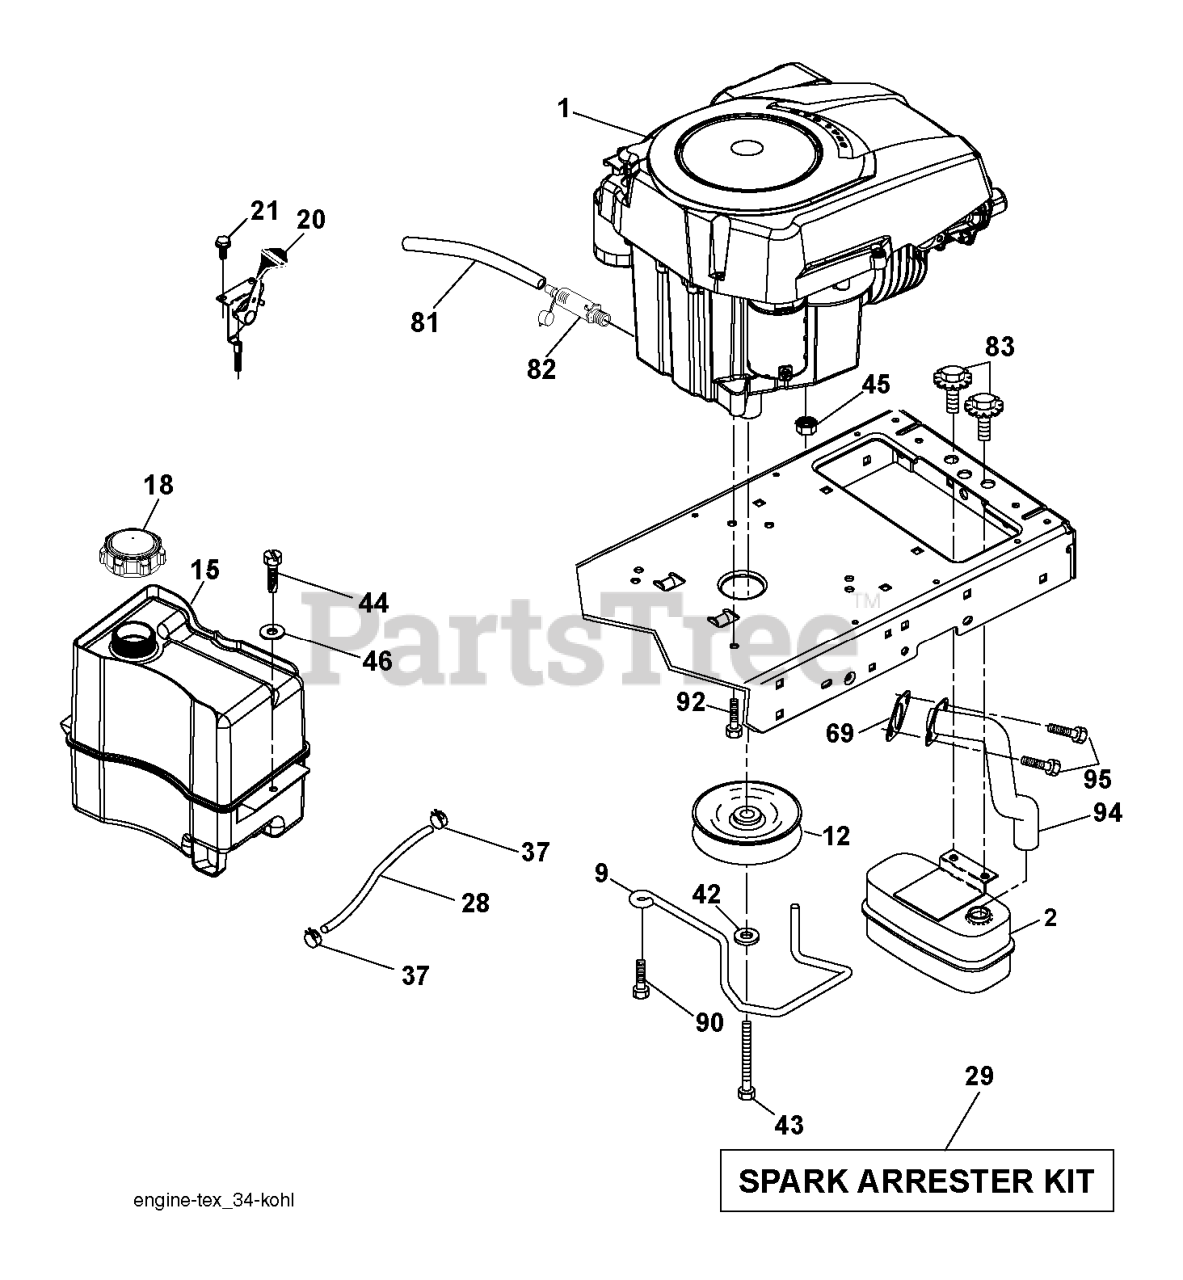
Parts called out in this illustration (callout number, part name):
2	MUFFLER.SINGLE.CYL.KOHL/B&S
9	KEEPER.BELT.ENGINE.3.25 (3 2)
12	PULLEY ENGINE
15	RP TANK FUEL FRT 1.5 GAL
18	FUEL CAP
20	CONTROL.TH/CK.C.
21	SCREW.#10 X 0.750.BOS
28	LINE.FUEL.20
29	KIT.SPARK ARRESTOR 794945 B&S
37	HOSE CLAMP
42	LOCKWASHER
43	BOLT HEX 7/16-20X4-1/4"
44	SCREW HEXWSHR 1/4-20X3/4
45	NUT
69	GASKET.EXHAUST.KOHLER
81	TUBE, DRAIN OIL ASM.
82	PLUG DRAIN OIL EASY
83	BOLT.5/16-18UNCX3/4 W/SEMS.BLK
90	SCREW 3/8-16X1
92	SCREW 3/8-16X1
94	RP.TUBE.EXHAUST.KOHL.COURAGE
95	SCREW.SOCKET HD.5/16-1
